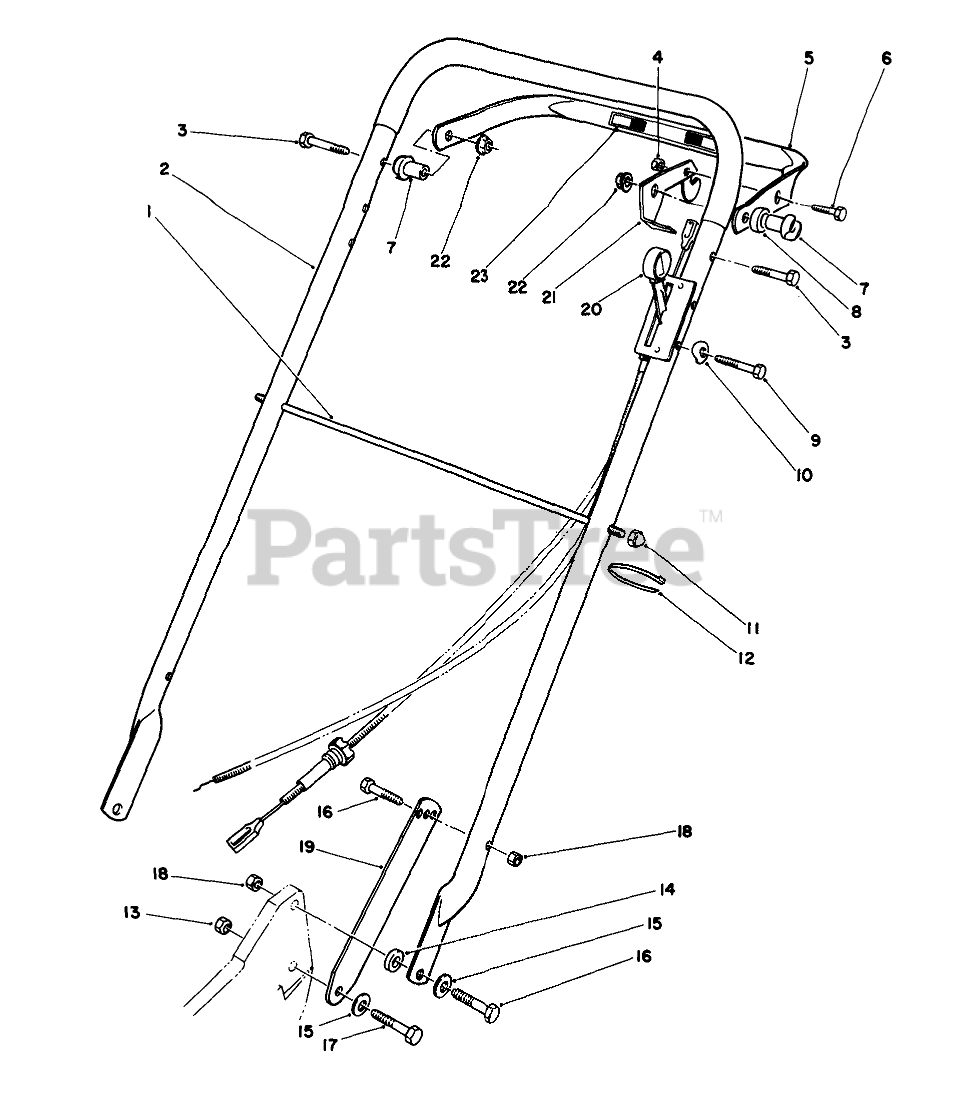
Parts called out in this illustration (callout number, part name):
1	ROD-SUPPORT, BAG
2	Handle
3	SCREW-HH
4	NUT-LOCK, NI
5	Bar-Control
6	SCREW-HH
7	SPACER-SUPPORT
8	SPACER-NYLON
9	SCREW-HH
10	WASHER
11	NUT-CAP
12	TIE-CABLE
13	NUT-LOCK, NI
14	SPACER-PIN, MOUNTING
15	WASHER-BELLEVILLE
16	SCREW-HH
17	SCREW-HH
18	NUT-LOCK, NI
19	HANDLE LATCH
20	Throttle Control Assembly (Model No. 22700C Only)
21	Lever-Control
22	NUT-HF
23	DECAL - INT'L TRACTION
